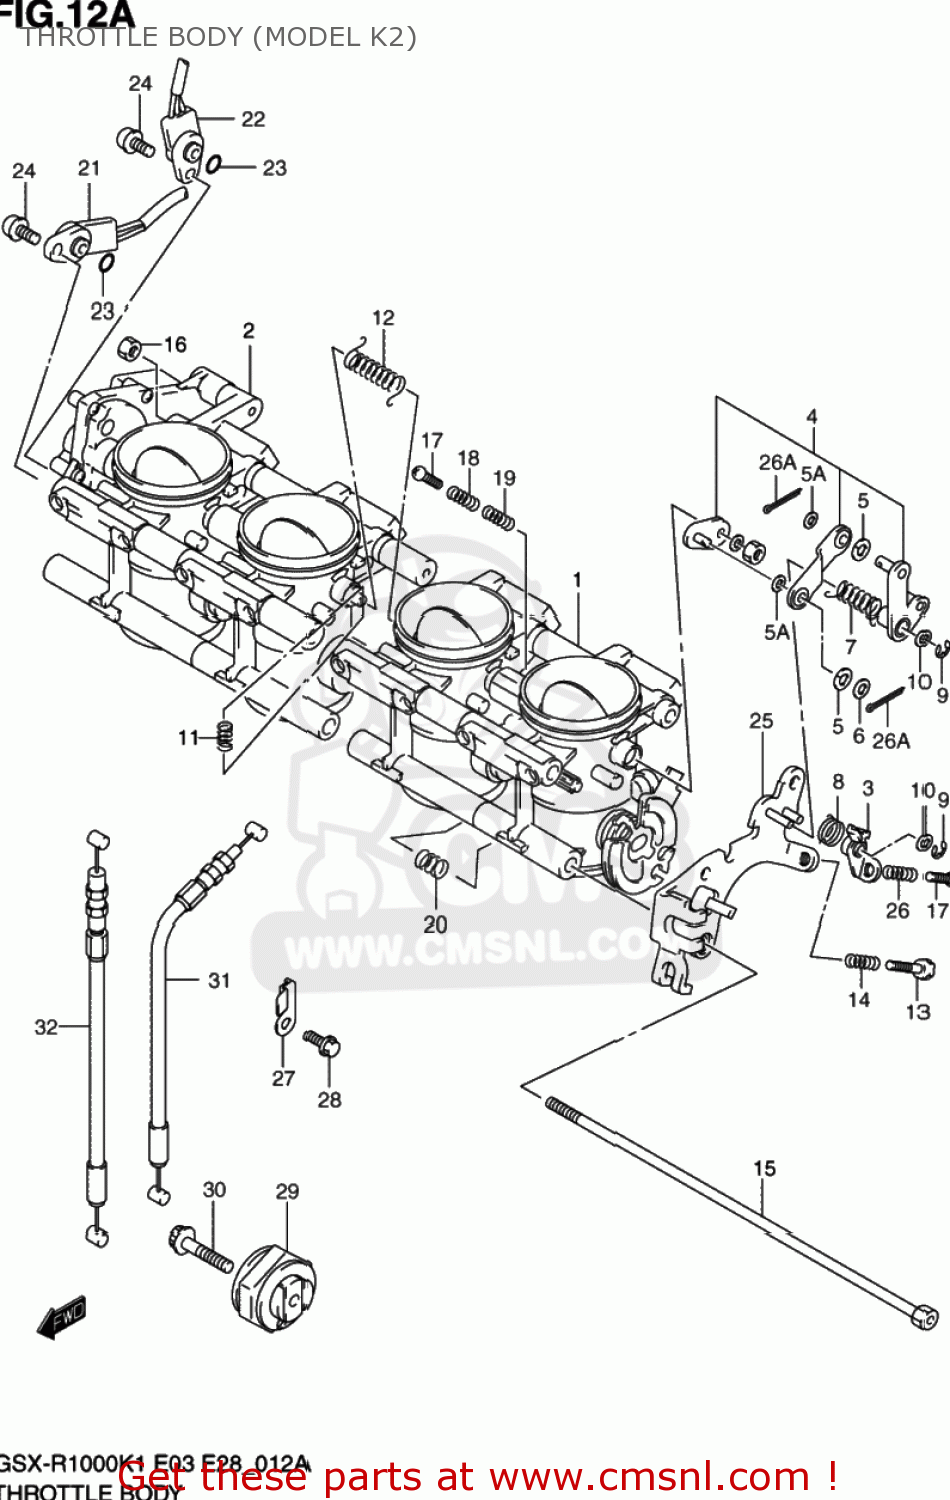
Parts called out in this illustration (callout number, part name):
1	CARB.SET
2	BODY SET,THROTTLE #3/#4
3	LEVER,LINK
4	LINK LEVER SET
5	WASHER
6	WASHER
7	SPRING
8	SPRING
9	E CLIP
10	WASHER
11	SPRING
12	SPRING
13	SCREW,STOP
14	SPRING
15	BOLT
16	NUT
17	SCREW,STOP
18	SPRING
19	SPRING
20	SPRING
21	SENSOR ASSY,TH
22	SENSOR ASSY,TH
23	O RING
24	SCREW
25	PLATE,STAY
26	SPRING
26A	PIN
27	BRACKET,EXHAUST VALVE CABLE
28	BOLT
29	PULLEY,CONTROLLER
30	BOLT
31	CABLE,EXHAUST VALVE NO.1
32	CABLE,EXHAUST VALVE NO.2
